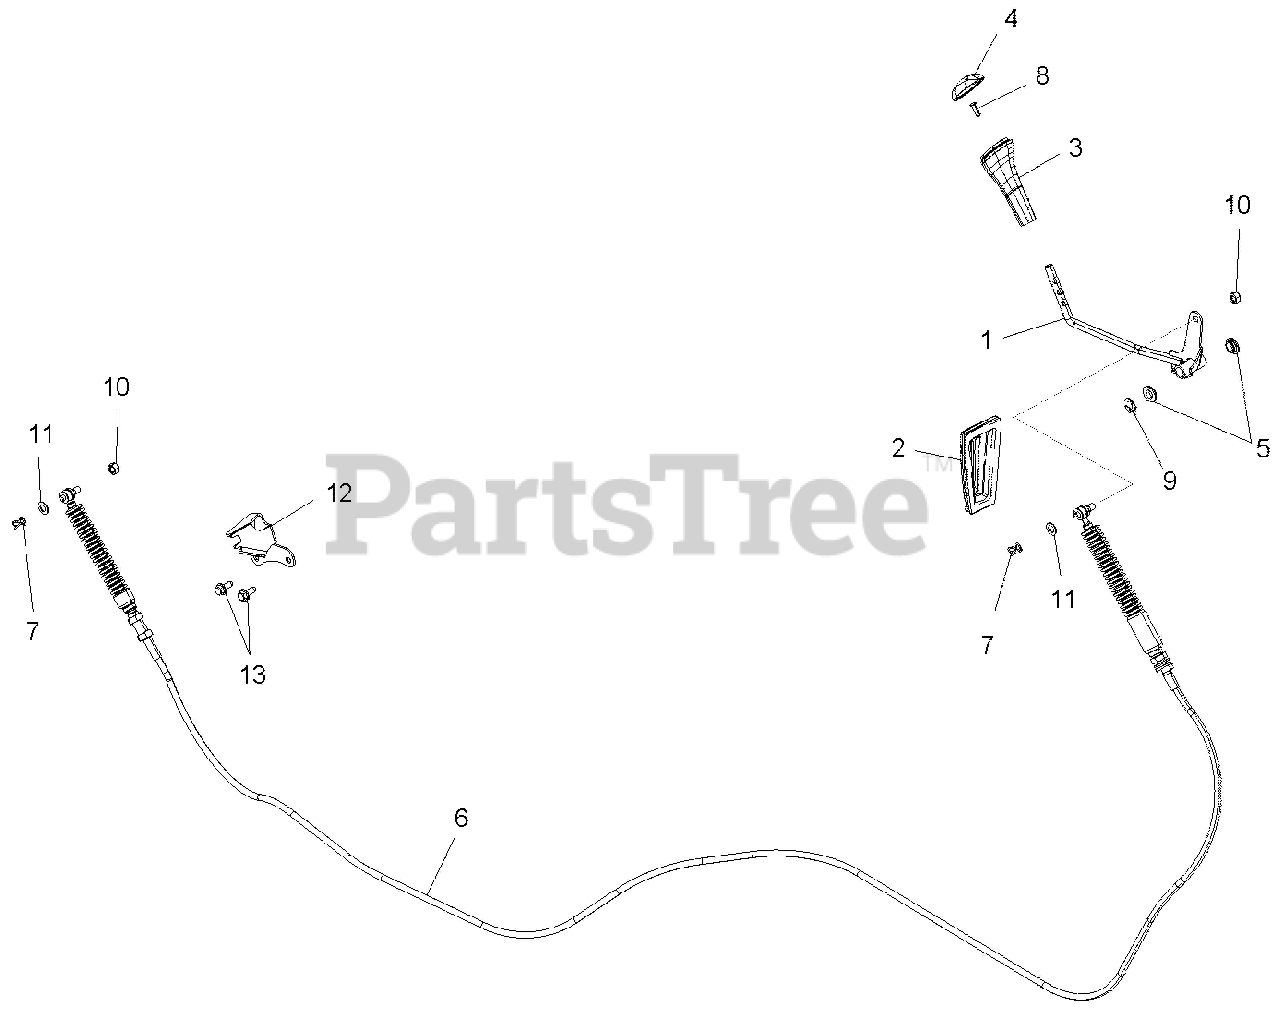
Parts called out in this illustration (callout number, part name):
1	WELD-SHIFT LEVER,BLK
2	GROMMET-SHIFT LEVER
3	KNOB-GEAR SELECTOR SHIFT
4	COVER-SHIFT
5	BUSHING-PEDAL PIVOT
6	CABLE, SHIFT
7	PIN-CLIP,14MM
10	NUT,NYLOK M8X1.25(10) *
11	WASHER,FLAT(10)
12	BRKT-SHIFT CABLE
13	BOLT-M10X1.25X16,HXHD,FLG
